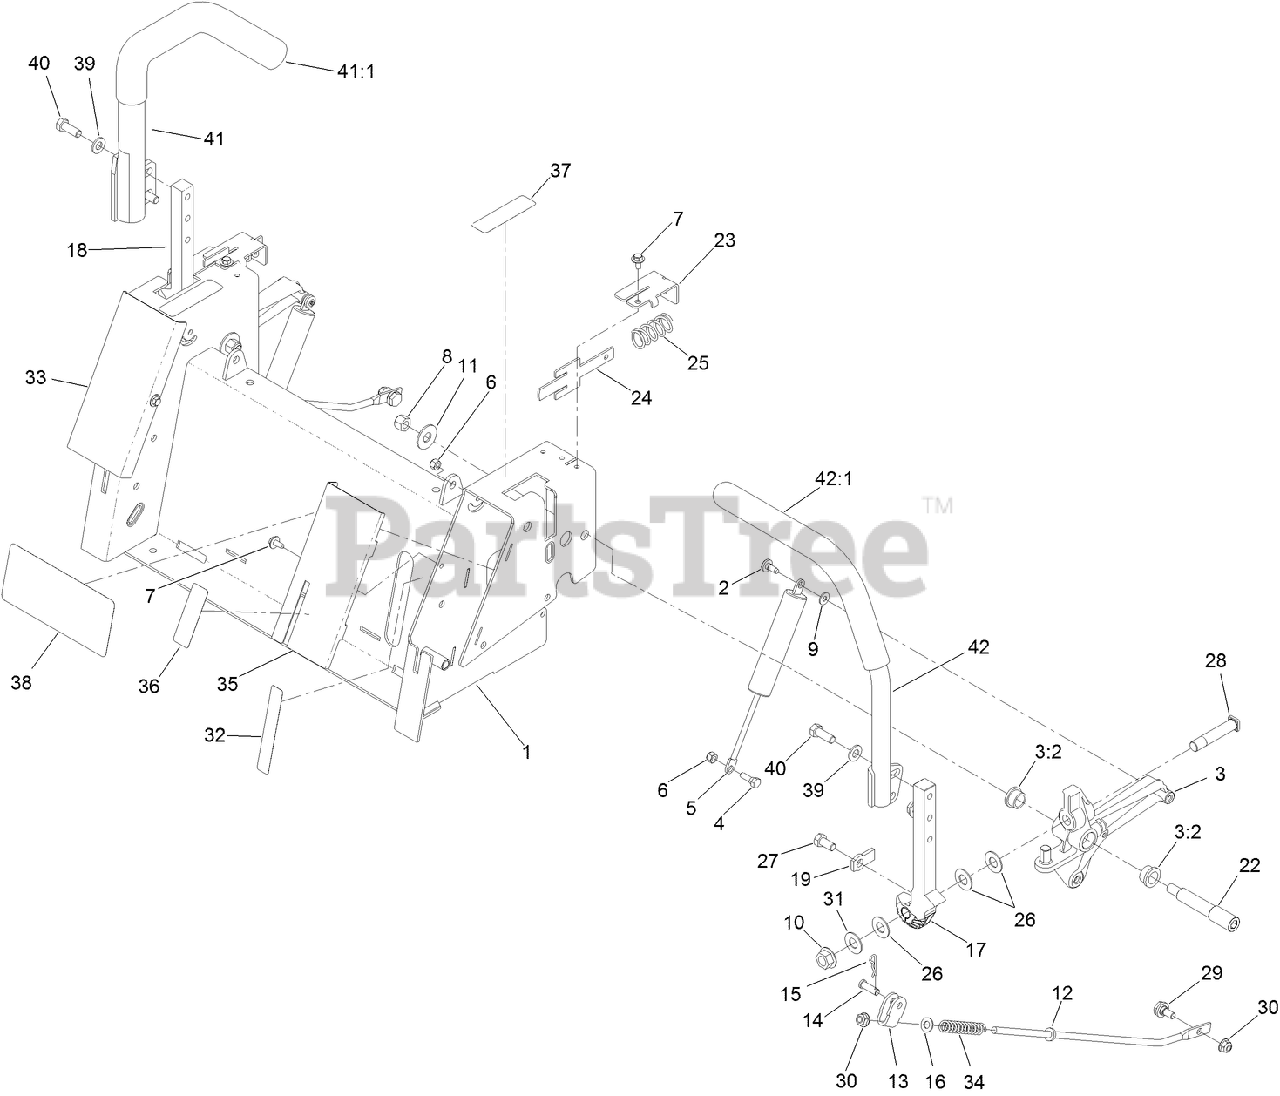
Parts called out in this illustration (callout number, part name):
1	BOX-CONTROL
2	SCREW-SHOULDER
3	ACTIVATOR ARM ASM
3:2	BUSHING
4	BOLT-SHOULDER
5	DAMPER
6	NUT-LOCK, NI
7	SCREW-HHFTF
8	NUT-LOCK, NI
9	WASHER
10	NUT-HF
11	WASHER-FLAT
12	ROD-CONTROL
13	BRACKET-CONTROL
14	PIN-CLEVIS
15	PIN-COTTER
16	WASHER-PLAIN
17	ARM-ACTUATOR, LH
18	ARM-ACTUATOR, RH
19	TAB-STOP
22	BOLT-SHOULDER
23	BRACKET-RETURN
24	PLATE-RETURN
25	SPRING-COMPRESSION
26	WASHER-PIVOT
27	SCREW-HH
28	BOLT-SHOULDER
29	BOLT-SHOULDER,HFH
30	NUT-HF, NI
31	WASHER-TEFLON
32	DECAL-FILL, FUEL
33	COVER-CONTROL, RH
34	SPRING-RETURN, NEUTRAL
35	COVER-CONTROL, LH
36	DECAL-BRAKE, PARKING
37	DECAL-CONTROL, MOTION
39	WASHER-FLAT
40	SCREW-HH
41	RH LEVER/GRIP ASM
41:1	GRIP-CONTROL, MOTION
42	LH LEVER/GRIP ASM
42:1	GRIP-CONTROL, MOTION
